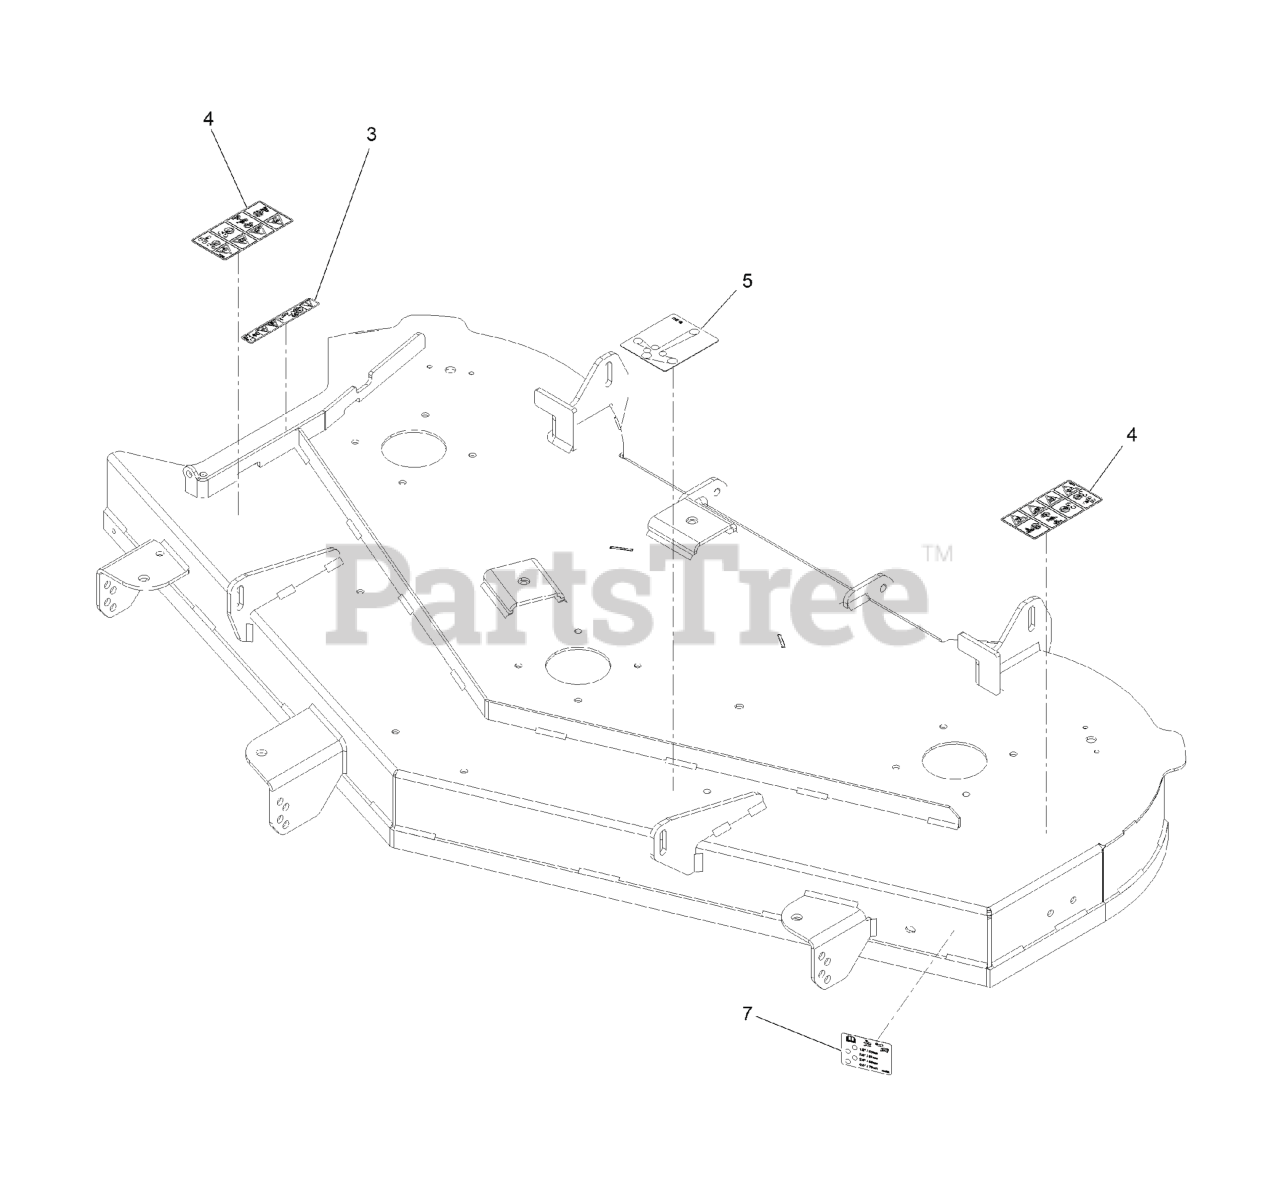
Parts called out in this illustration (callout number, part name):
3	DECAL-DANGER
4	DECAL-DANGER, DECK
5	DECAL-ROUTING, BELT
7	DECAL-SCALP, ANTI
